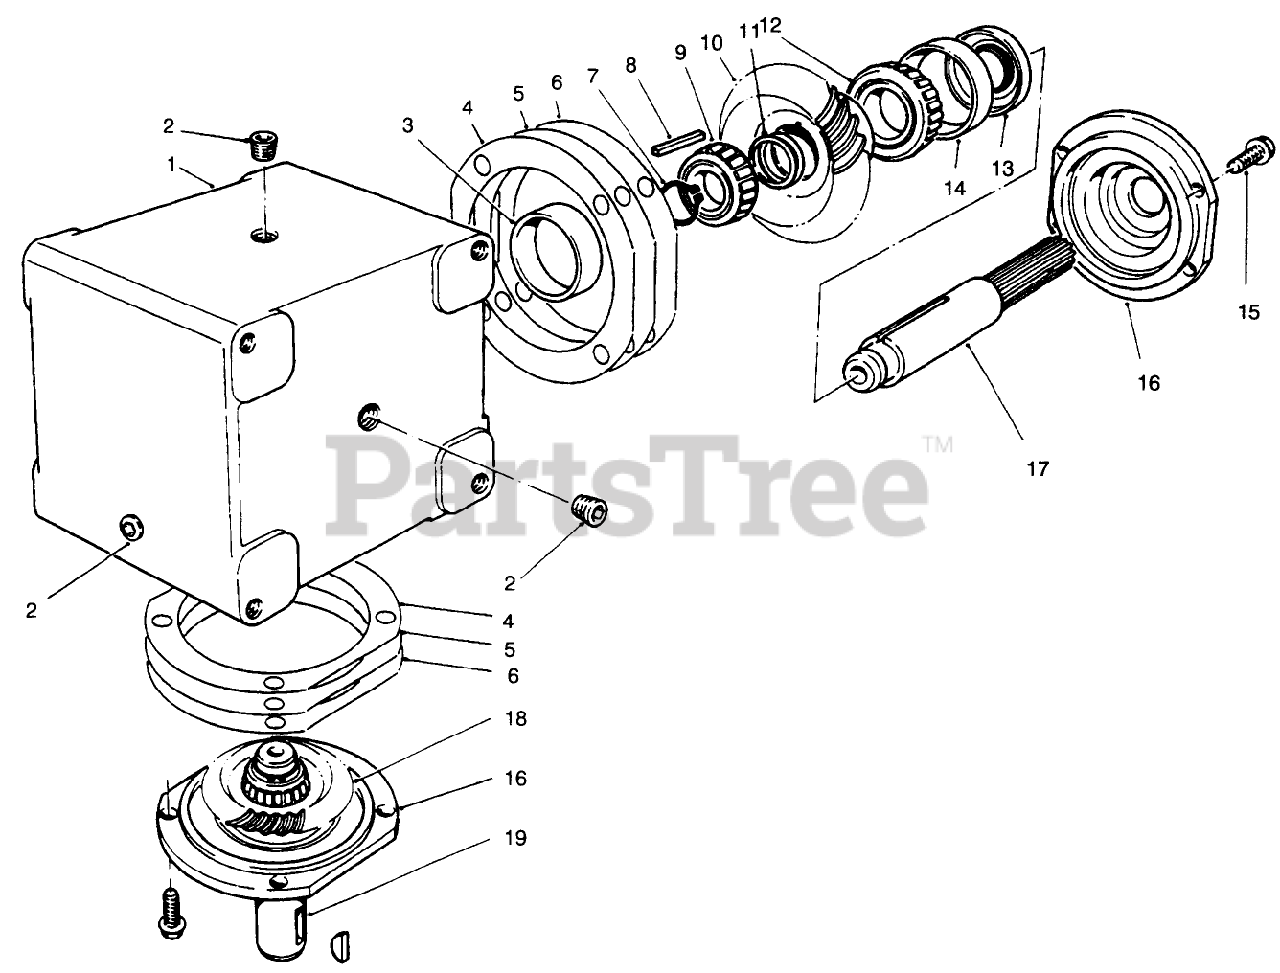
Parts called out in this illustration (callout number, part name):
1	HOUSING
2	PLUG (OBS, C/R TO 281-10)
3	Bearing Cup
4	GASKET
5	GASKET
6	GASKET
7	Ring-Retaining
8	Key
9	Cone
12	Cone
13	Seal
14	Cup
15	SCREW-HH (OBS, C/R TO 3234-5)
17	Shaft
19	Shaft
